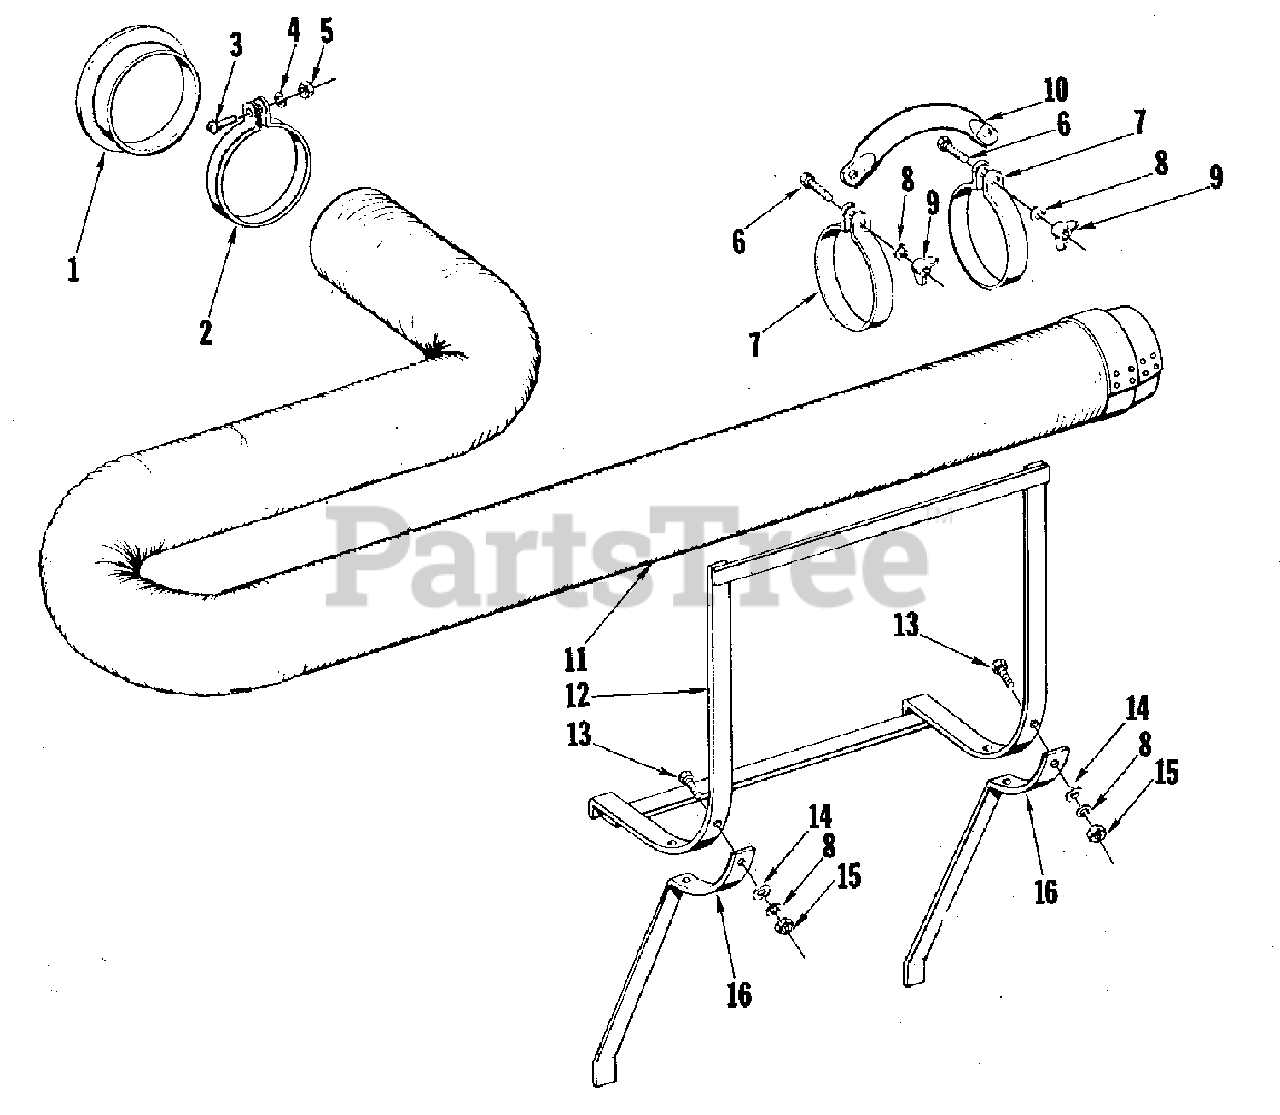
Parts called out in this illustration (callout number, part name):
1	FLANGE, Hose
3	SCREW, Machine, 1/4-20 x 3
4	WASHER, Lock, 1/4
5	NUT, Hex, 1/4-20
6	SCREW, Cap, 5/16-18 x 3/4
8	WASHER, Lock, 5/16"
9	NUT, Wing, 5/16-18
10	HANDLE, Hose
11	HOSE ASSEMBLY
12	CARRIER ASSEMBLY, Hose
13	SCREW, Cap, 5/16-18 x 7/8
14	WASHER, Flat, 5/16
15	NUT, Hex, 5/16-18
16	SUPPORT, Carrier
